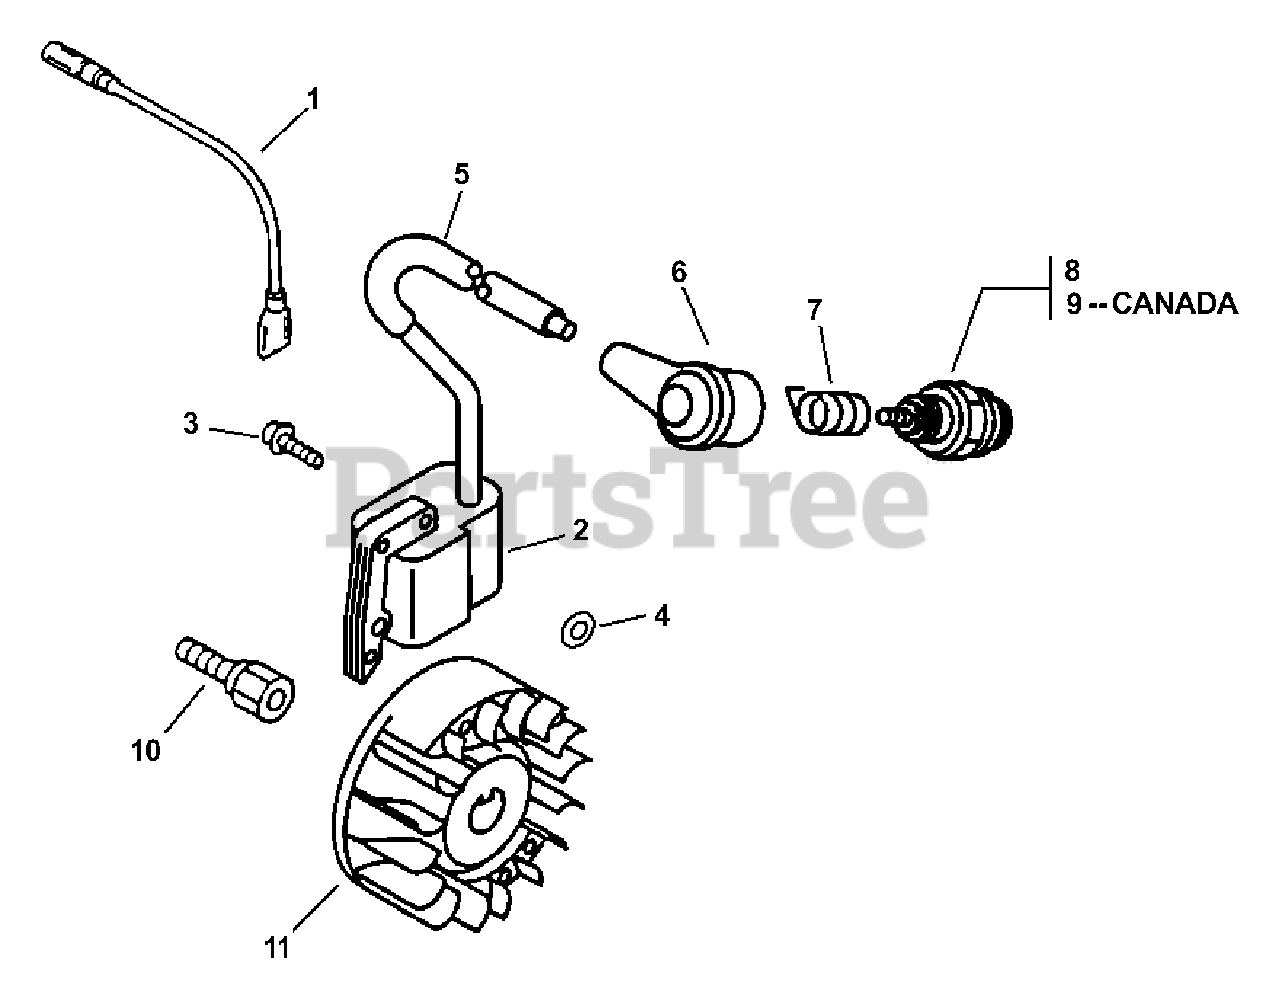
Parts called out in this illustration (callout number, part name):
1	LEAD
2	COIL, IGNITION
3	SCREW 4×22
6	CAP, SPARK PLUG
7	TERMINAL, SPARK PLUG
8	SPARK PLUG - BPM-7Y
9	SPARK PLUG - BPMR7A
10	HUB, FAN
11	FLYWHEEL
